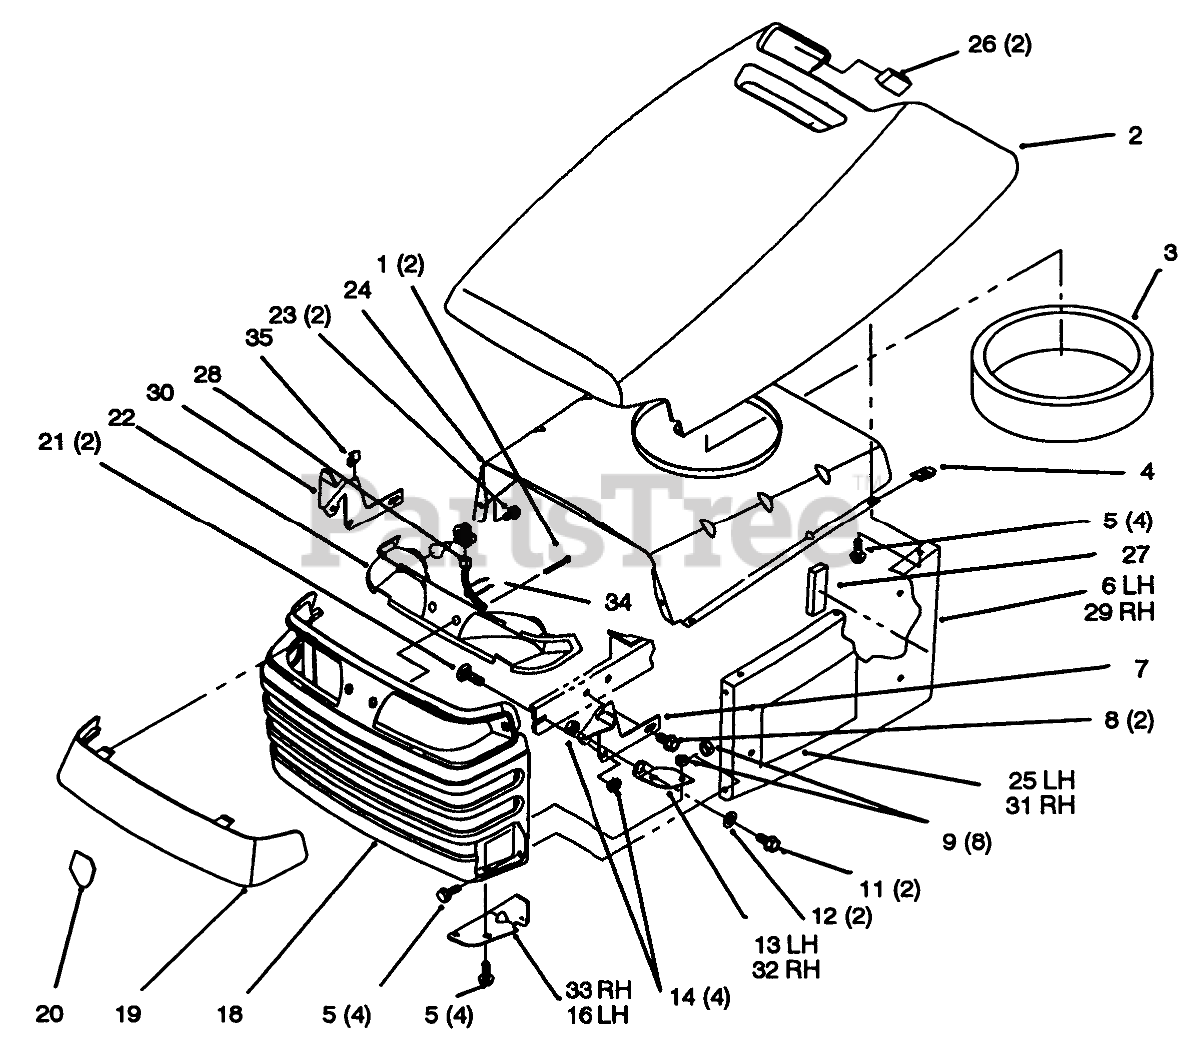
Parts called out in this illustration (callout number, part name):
2	HOOD ASM
3	Inlet-Seal Air (Only On: 72103, 72083)
3	Inlet-Seal Air (Only On: 72043, 72042, 72063, 72062)
5	SCREW-HWH
6	HOOD-SIDE, LH
7	BRACKET-HINGE, LH
8	SCREW-HWHTF
9	NUT-LOCK, HHF
11	SCREW-HH
12	BUSHING
13	HINGE-HOOD, LH
14	NUT-LOCK, NI
16	BRACKET-HOOD HINGE, RH
18	Screen/Grill ASM
19	LENS - HEADLIGHT
20	EMBLEM-HORSEHEAD
21	BOLT-CARR
22	HEADLIGHT REFLECTOR ASM
23	SCREW-PLASTITE
24	BAFFLE-HOOD, UPPER
25	DECAL - LH HOOD
26	Foam-Hood
27	FOAM-SIDEPANEL
28	HARNESS-WIRE, LIGHTS
29	HOOD-SIDE, RH
30	BRACKET-HINGE, RH
31	DECAL - RH HOOD
32	HINGE-HOOD, RH
33	BRACKET-HOOD HINGE, LH
34	TIE-CABLE
35	CLIP-RETAINER, WIRE
